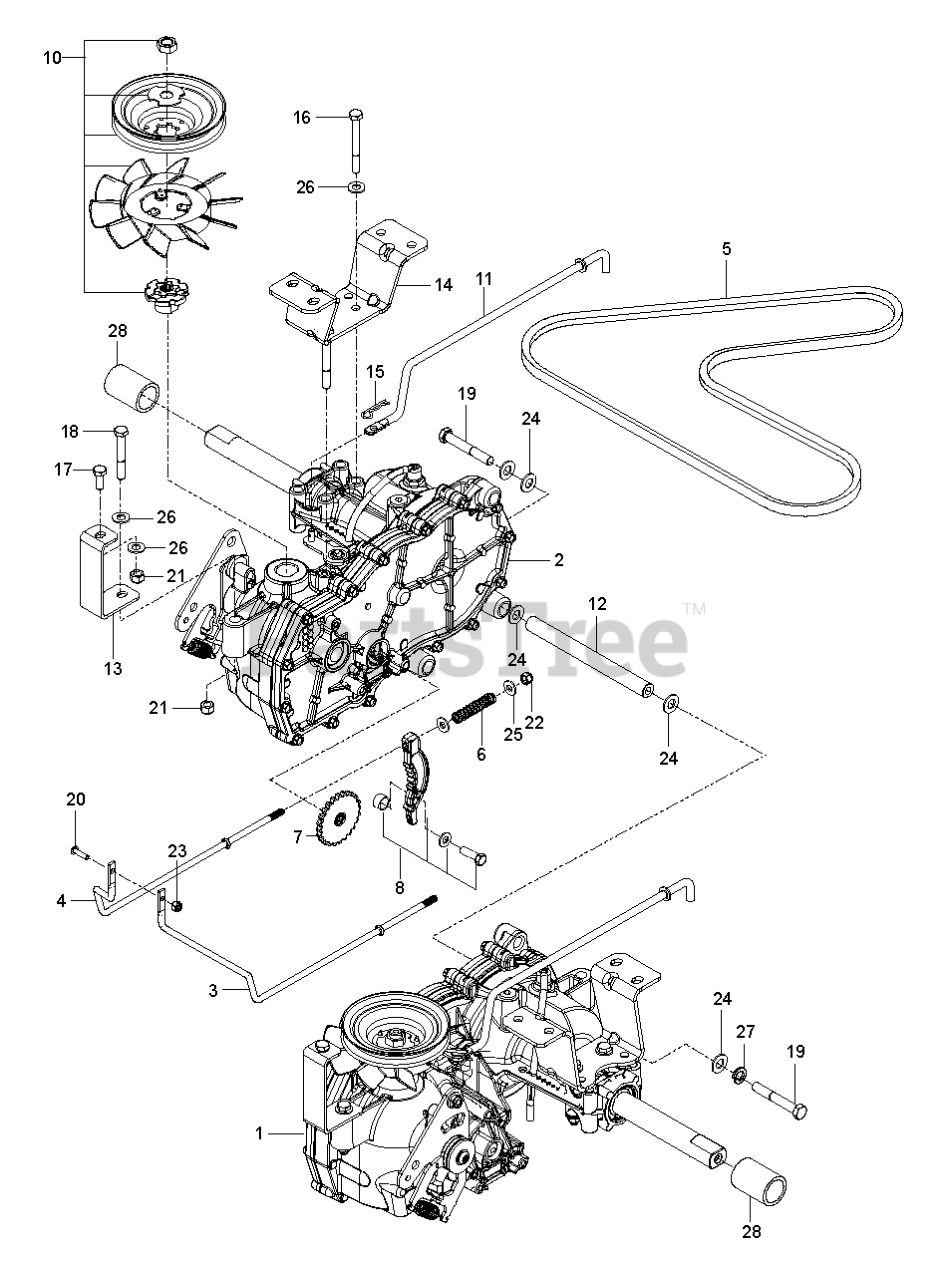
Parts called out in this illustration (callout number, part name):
1	TRANSMISSION EZT; DD; LONG; LE
2	TRANSMISSION EZT; DD; LONG; RI
3	LINKAGE.BRAKE.LT
4	LINKAGE, BRAKE RT
5	BELT, HYDRO PUMP
6	SPRING
7	HG_DISC COG BRAKE
8	HG_KIT BRAKE ARM (EZT)
10	KIT FAN/PULLEY 72137
11	LINKAGE, BYPASS, EZT
12	SPACER TUBE EZT
13	SUPPORT.FRONT.TRANS.PNTX431
14	BRACKET.EZT.MOUNT.REAR.PNTX431
15	HAIRPIN #2
16	Bolt Fin Hex 5/16 - 18 UNC x 2.75 (AYP part number)
17	HCS 5/16C X 3/4
18	Bolt Fin Hex 5/16-18 x 2-1/4 (AYP part number)
19	HCS 3/8C X 2 1/2
20	SCREW.TRSHD.SL.#10-24UNC X
21	Locknut, Hex, with Washer Insert 5/16-18 (AYP part number)
22	NUT 1/4-20 NYLOC
23	NUT 10-24 NYLOC
24	Washer 13/32 x 1-3/16 x 12 Gauge (AYP part number)
25	Washer 9/32 x 5/8 x 16 Gauge (AYP part number)
26	Washer, Nut Lock Hex w/Ins. 5/6-18 (AYP part number)
27	SLW 3/8 STD
28	COVER EZT DD AXLE COVER 11.52
